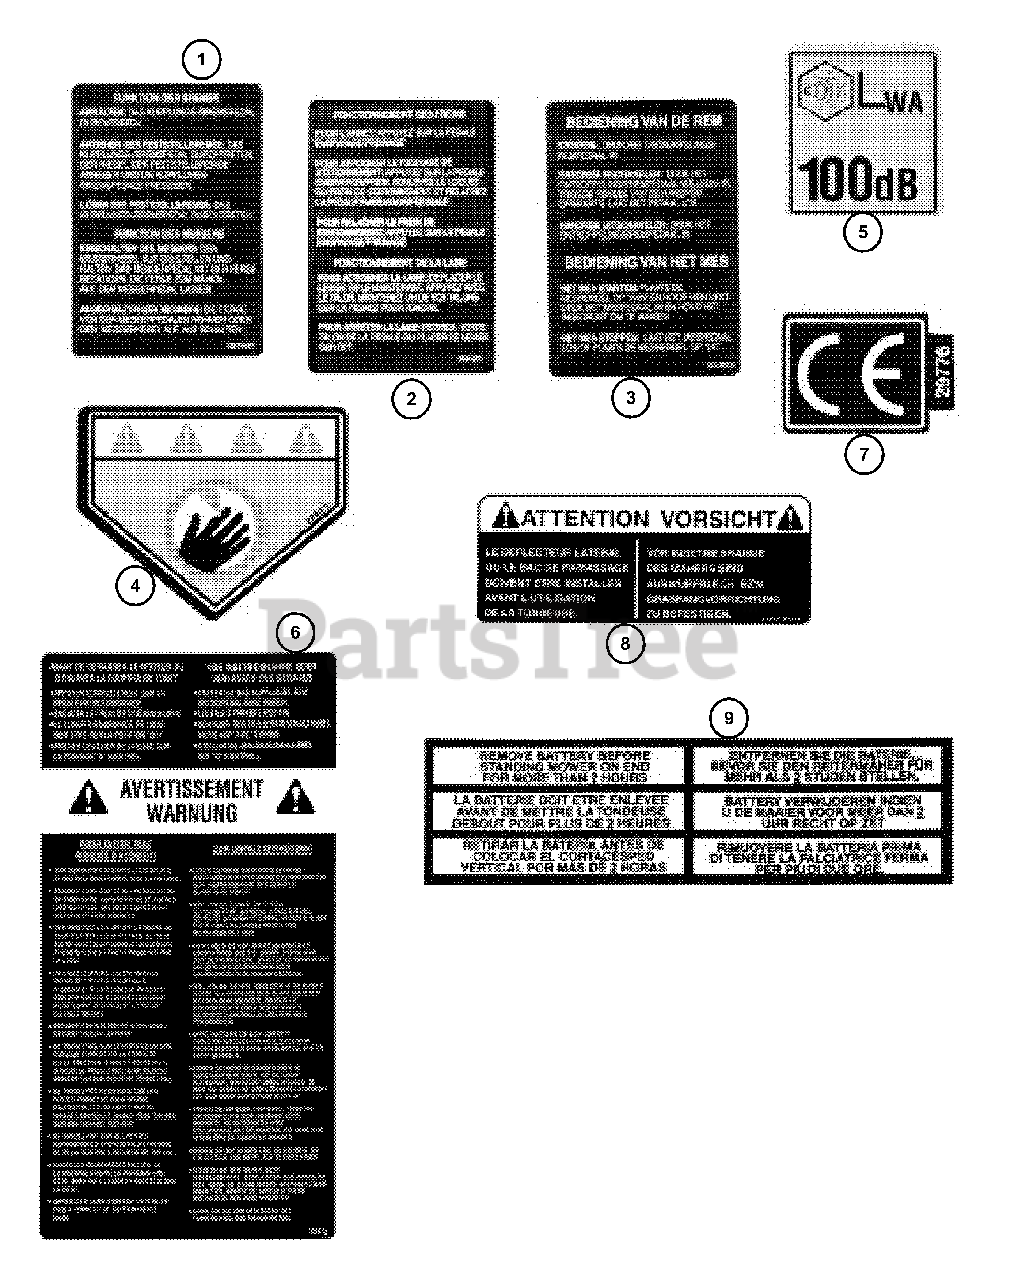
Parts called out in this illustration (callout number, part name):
1	DECAL, Brake Operation (German)
2	DECAL, Brake Operation (French)
3	DECAL, Brake Operation (Dutch)
4	DECAL, WARNING
5	DECAL, European Noise Control
6	DECAL, SAFETY Instruction (German & French)
7	DECAL, European Community
8	DECAL, Deflector (German & French)
9	DECAL, Battery Storage
